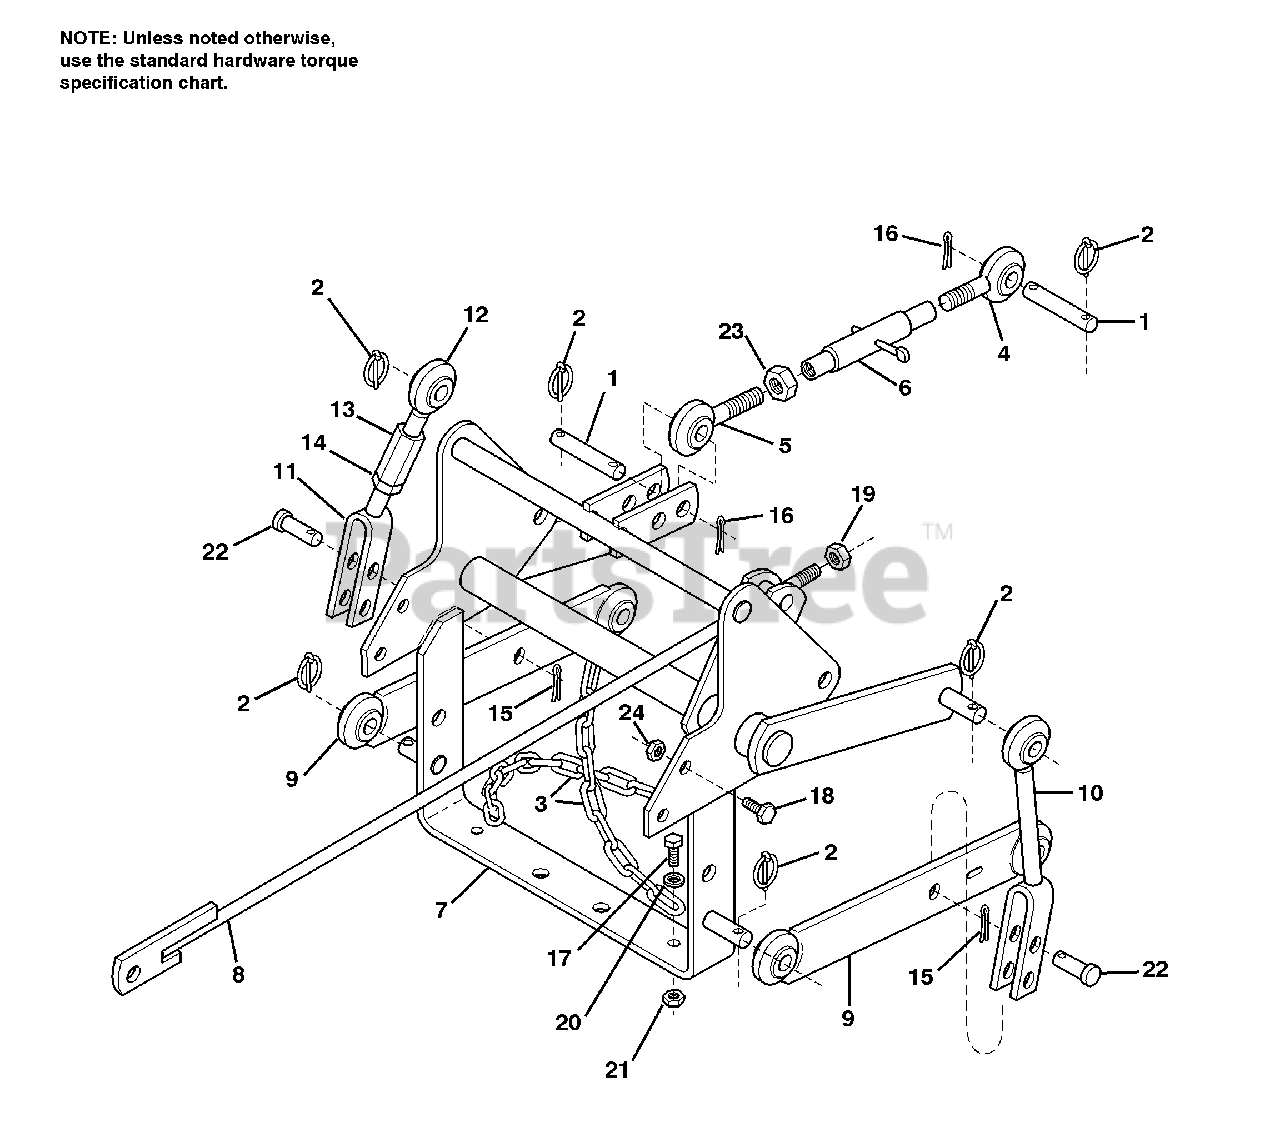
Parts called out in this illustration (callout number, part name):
3	CHAIN, Sway
4	STUD, Eyelet, LH Thread
5	STUD, Eyelet, RH Thread
6	TUBE ASSEMBLY
7	HITCH ASSEMBLY
8	LIFT ROD ASSEMBLY
10	CLEVIS ASSEMBLY, LH
11	CLEVIS ASSEMBLY, RH
12	BALL JOINT ASSEMBLY, Upper RH
14	NUT, Hex Jam, 5/8-18
15	PIN, Cotter, 1/4 x 1
16	PIN, Cotter, 1/4 x 1-1/2
17	CAPSCREW, Hex Hd, 3/8-16 x 1-1/4
18	CAPSCREW, Hex Hd, 1/2-13 x 1-1/4
19	NUT, Lock, 1/2-13
20	WASHER, 3/8
21	NUT, Hex Lock, 3/8-16
22	PIN, Clevis, 5/8 x 2-1/4
23	NUT, Hex Jam, 3/4-10
24	NUT, Hex Lock, 1/2-13
